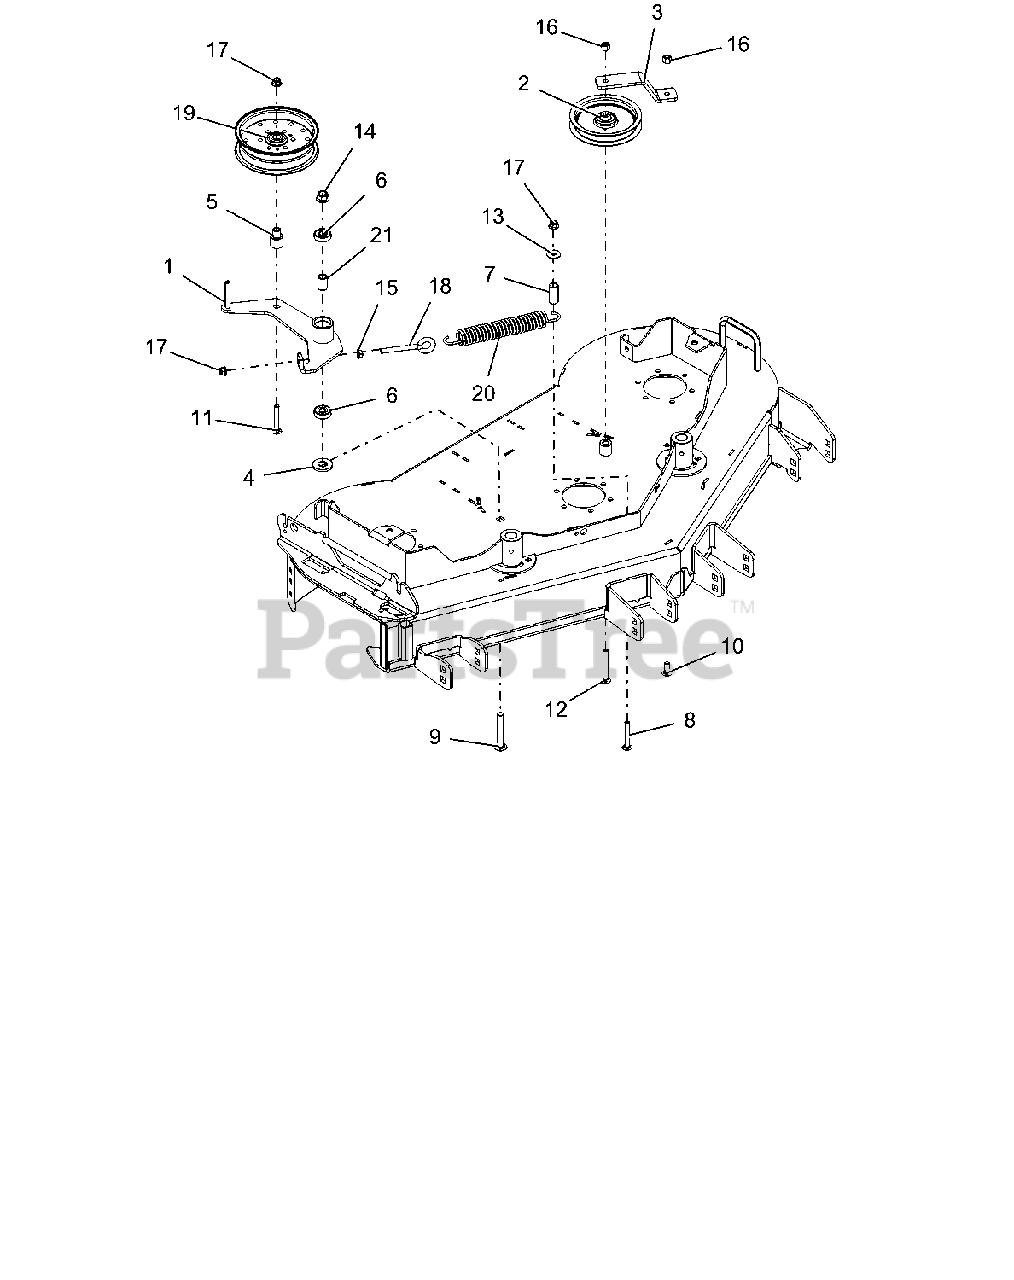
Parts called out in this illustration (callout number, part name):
1	WLDMT, IDLER ARM 52/48 FLWLK (BLACK)
2	IDLER, FLAT - 5.00" X .75"
3	STRAP, IDLER 48/52 WALK-BLACK
4	SPACER, IDLER ARM
5	SPCR, IDLER
6	BRG-BALL .500X1.375X.44
7	BSHG-SLV .500X.750X1.560
8	BLT-RHDSSQNK .38-16X2.50 G5YZ
9	BLT-RDHDSQSHNK .50-13X3.25 YWZC
10	BLT-RDHDSHSQNK.38-16X1.0 G5YZ
11	BLT-RDHDSQNK .38-16X2.50 G5 Y
12	BLT-RDHDSQNK .38-16X3.00 G5 YWZC
13	WSHR-FL-STL .375X1.125X.065YWZ
14	NUT-LK-NYL-FLG .50-13 YWZC
15	@NUT-SPNLK-FLG .375-16 YWZC
16	NUT-LK-NYL .38-16 YWZC
17	NUT-LK-NYL-FLG .38-16 YWZC
18	BOLT, EYE .38-16X4.50 .75 DIA
19	PULLEY, FLAT IDLER 6.00 X .635
20	SPRG, EXTENSION
21	SPACER, .510 X .750 X 1.148
